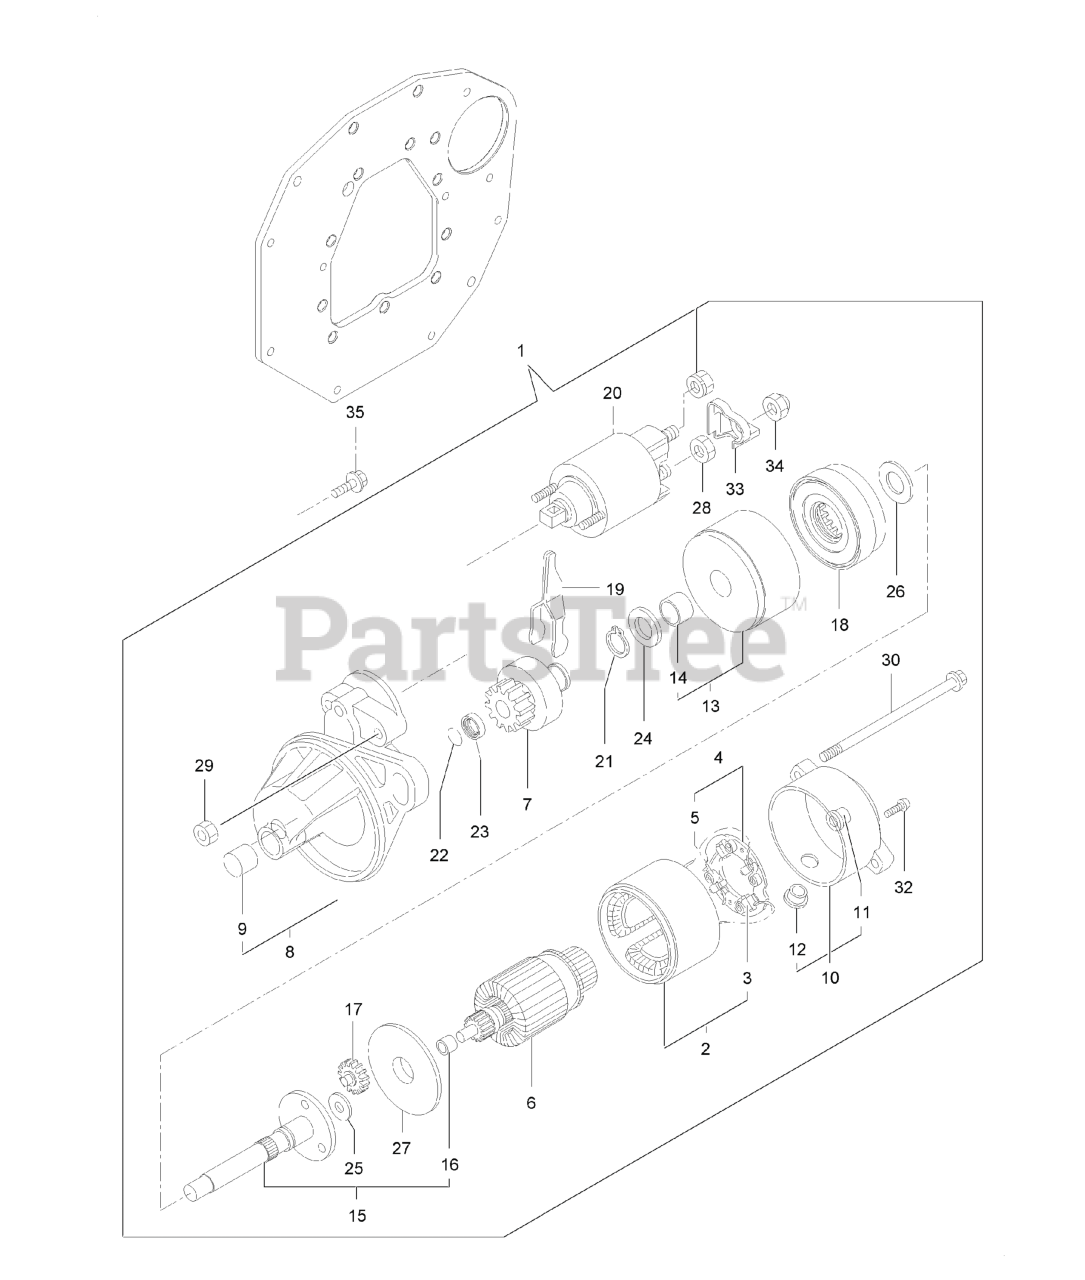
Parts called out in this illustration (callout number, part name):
1	STARTER ASM
2	YOKE ASM
3	STARTER KIT
4	HOLDER ASM
6	ARMATURE ASM
7	CLUTCH ASM
8	HOUSING ASM
9	BEARING, NEEDLE 1
10	FRAME ASM
11	BEARING
13	BEARING ASM
14	Bearing
15	SHAFT ASSY 1
16	Bearing
20	SWITCH ASM
30	BOLT-THROUGH
33	COVER-TERMINAL
